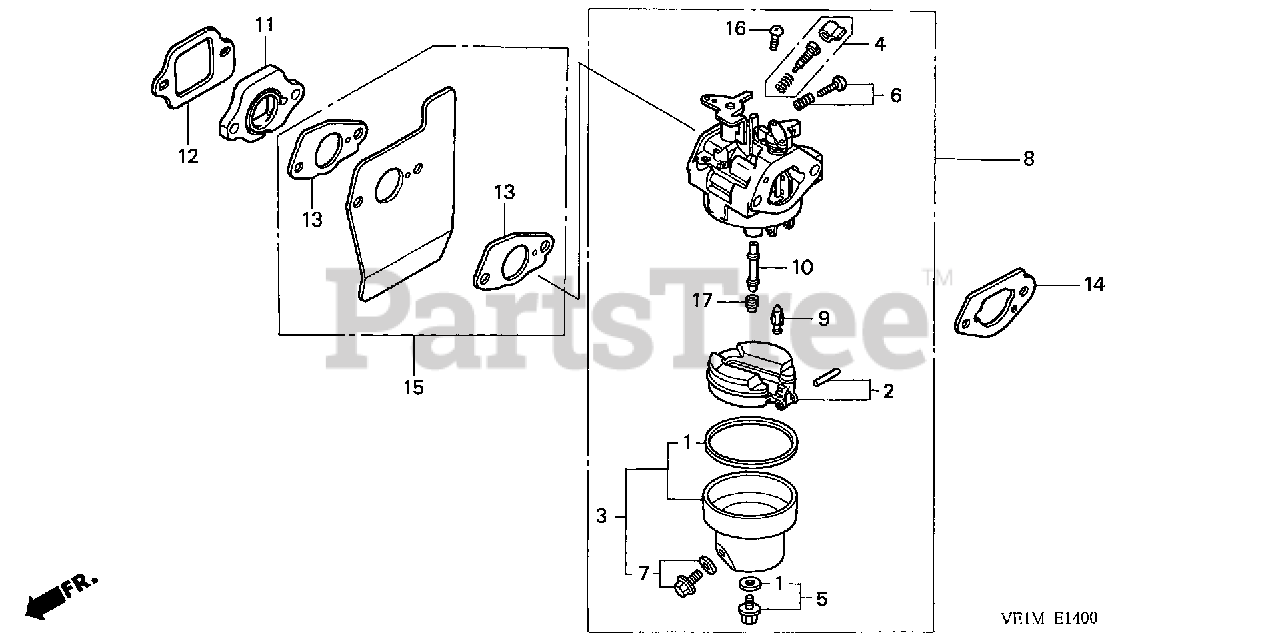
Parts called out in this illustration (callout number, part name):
1	GASKET SET
3	CHAMBER SET, FLOAT
5	SCREW SET
6	SCREW SET (THROTTLE STOP)
7	SCREW SET, DRAIN
8	CARBURETOR ASSY. (BB62B D)
8	CARBURETOR ASSY. (BB62B E)
9	VALVE, FLOAT (CARBURETOR NO.)
10	NOZZLE, MAIN
11	INSULATOR, CARBURETOR
12	GASKET, INSULATOR
13	GASKET, CARBURETOR
14	GASKET, CARBURETOR
15	GUIDE, AIR
16	SCREW, PAN (5X6)
17	JET, MAIN (#60)
17	JET, MAIN (#62)
17	JET, MAIN (#65)
